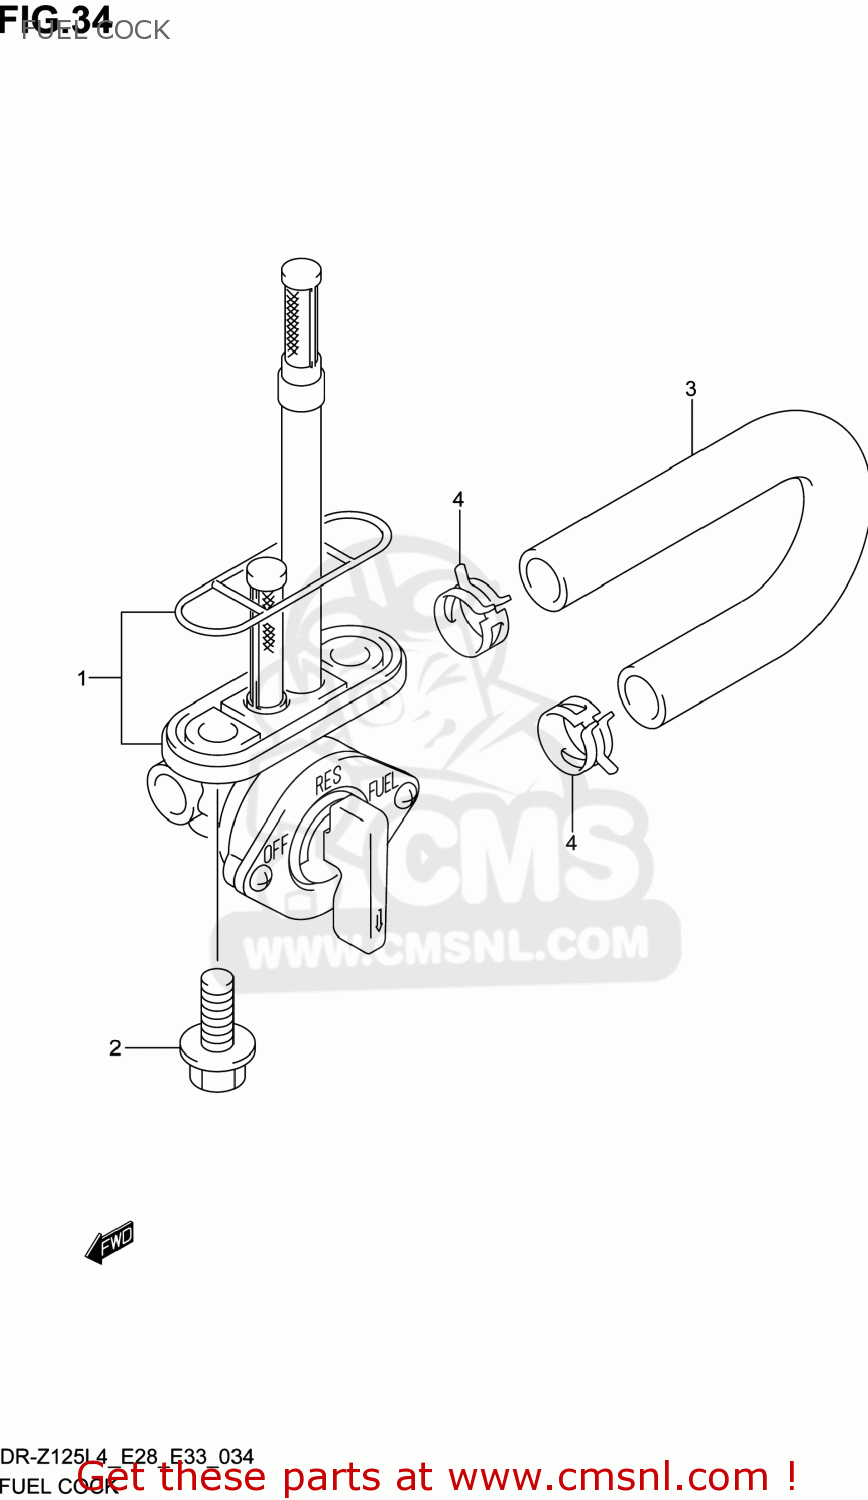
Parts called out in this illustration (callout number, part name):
1	COCK ASSY,FUEL
2	BOLT
3	HOSE,FUEL
4	CLIP
